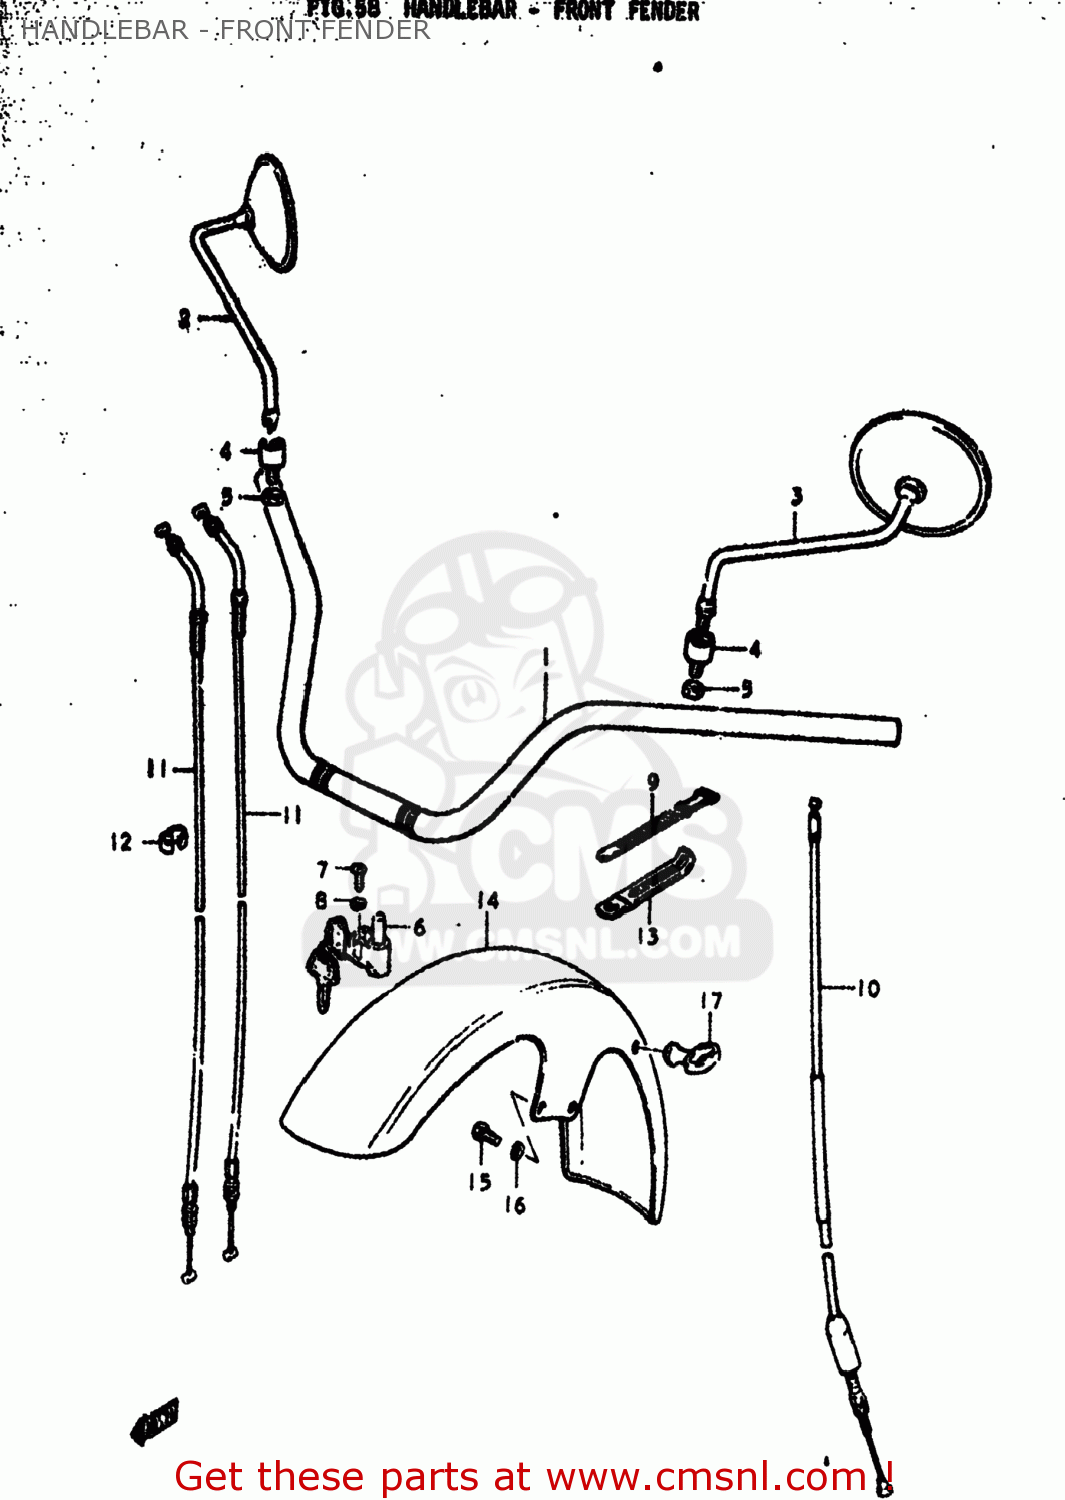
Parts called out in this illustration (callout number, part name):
1	HANDLEBAR,RIGHT
2	MIRROR ASSEMBLY,RIGHT
3	MIRROR ASSEMBLY,LEFT
4	CUSHION,REAR VIEW MIRROR
5	NUT
6	LOCK ASSEMBLY,STEERING
7	SCREW
8	LOCK WASHER
9	CLAMP(L:120)
10	CABLE ASSEMBLY,CLUTCH
11	CABLE ASSY,THROTTLE
12	CLIP
13	CLAMP
14	FENDER,FR
15	BOLT
16	LOCK WASHER
17	GUIDE,CABLE
